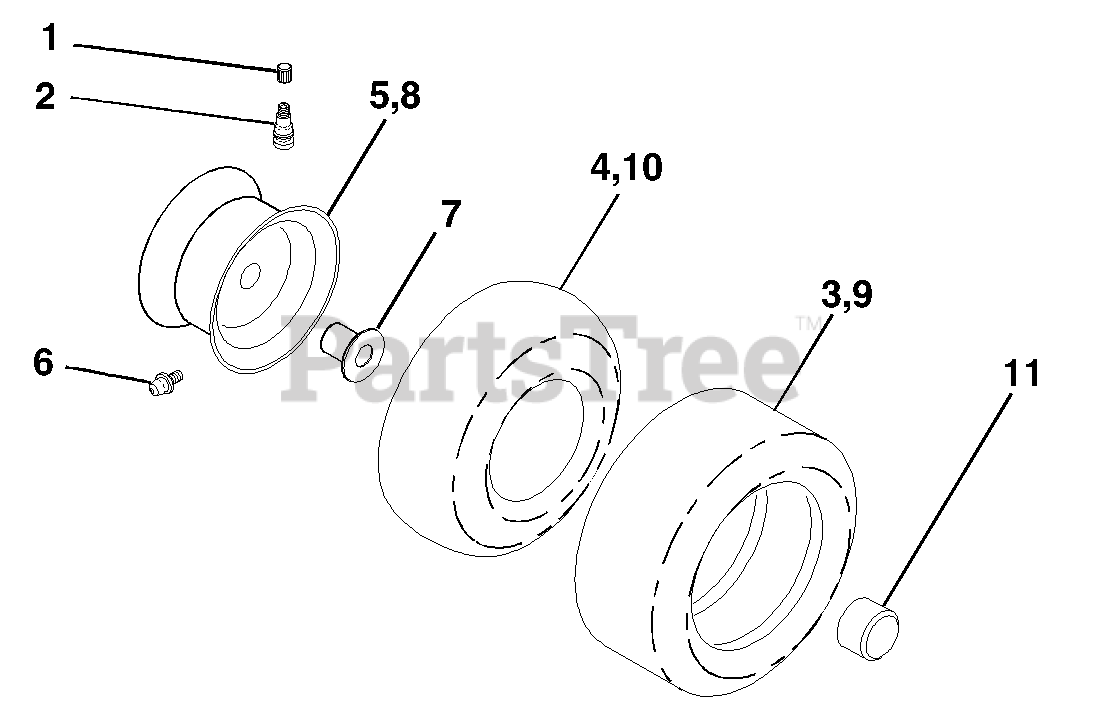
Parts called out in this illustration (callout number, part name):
1	Cap Valve Tire
2	Stem Valve
3	Tire F Ts 15 X 6 0 - 6 Service
4	Tube Front (Service Item Only)
5	Rim Asm 6" front Silver Service
6	Fitting Grease (Front Wheel Only)
7	Bearing Flange (Front Wheel Only)
8	Rim Asm 8" rear Silver Service
9	Tire R Ts 18x9 5-8 C Service
10	Tube Rear (Service Item Only)
11	Cap Axle Blk 1 50 X 1 00
